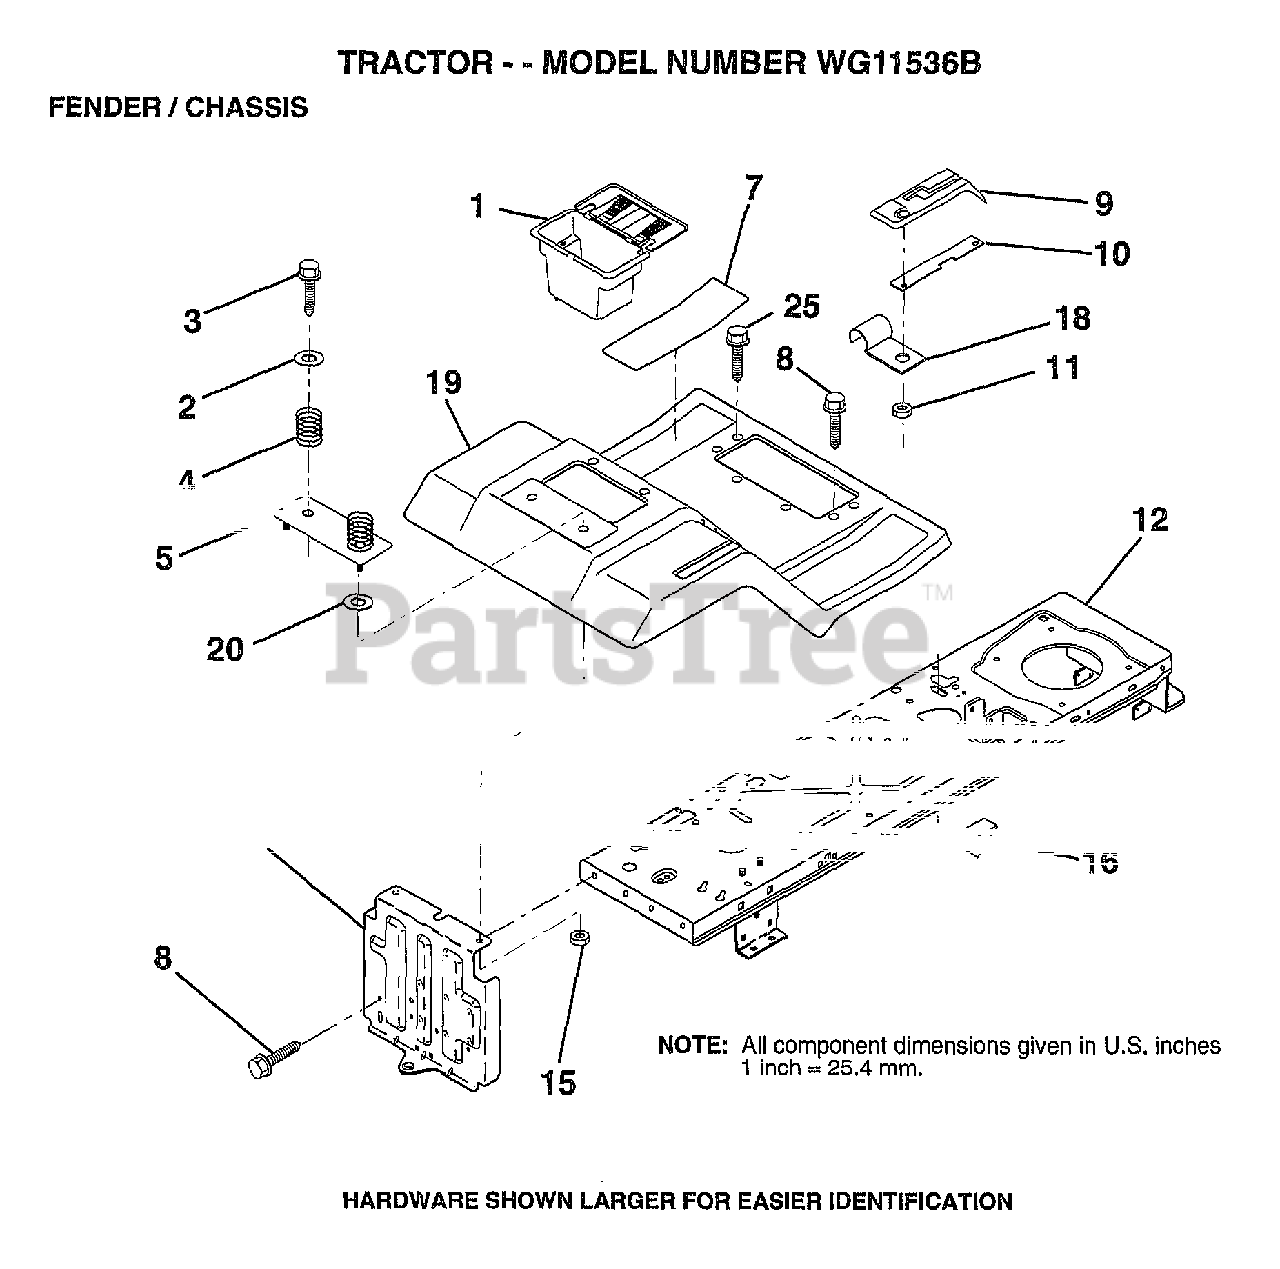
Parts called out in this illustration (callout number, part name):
1	"CASE,BATTERY.MECH"
2	WASHER
3	SCREW
4	SPRING COMPRESSIO
5	PLATE.FEND.LR.ASM
7	PAD FOOTREST
8	SCREW
9	CONSOLE SHIFT
10	PLATE LOCK SHIFT
11	NUT
12	CHASSIS.WELD.ASM.
15	NUT HXKEP 1/4X20
17	DRAWBAR ASM LR
18	"CLIP,INSULATOR"
19	FENDER/FOOTREST
25	SCREW
